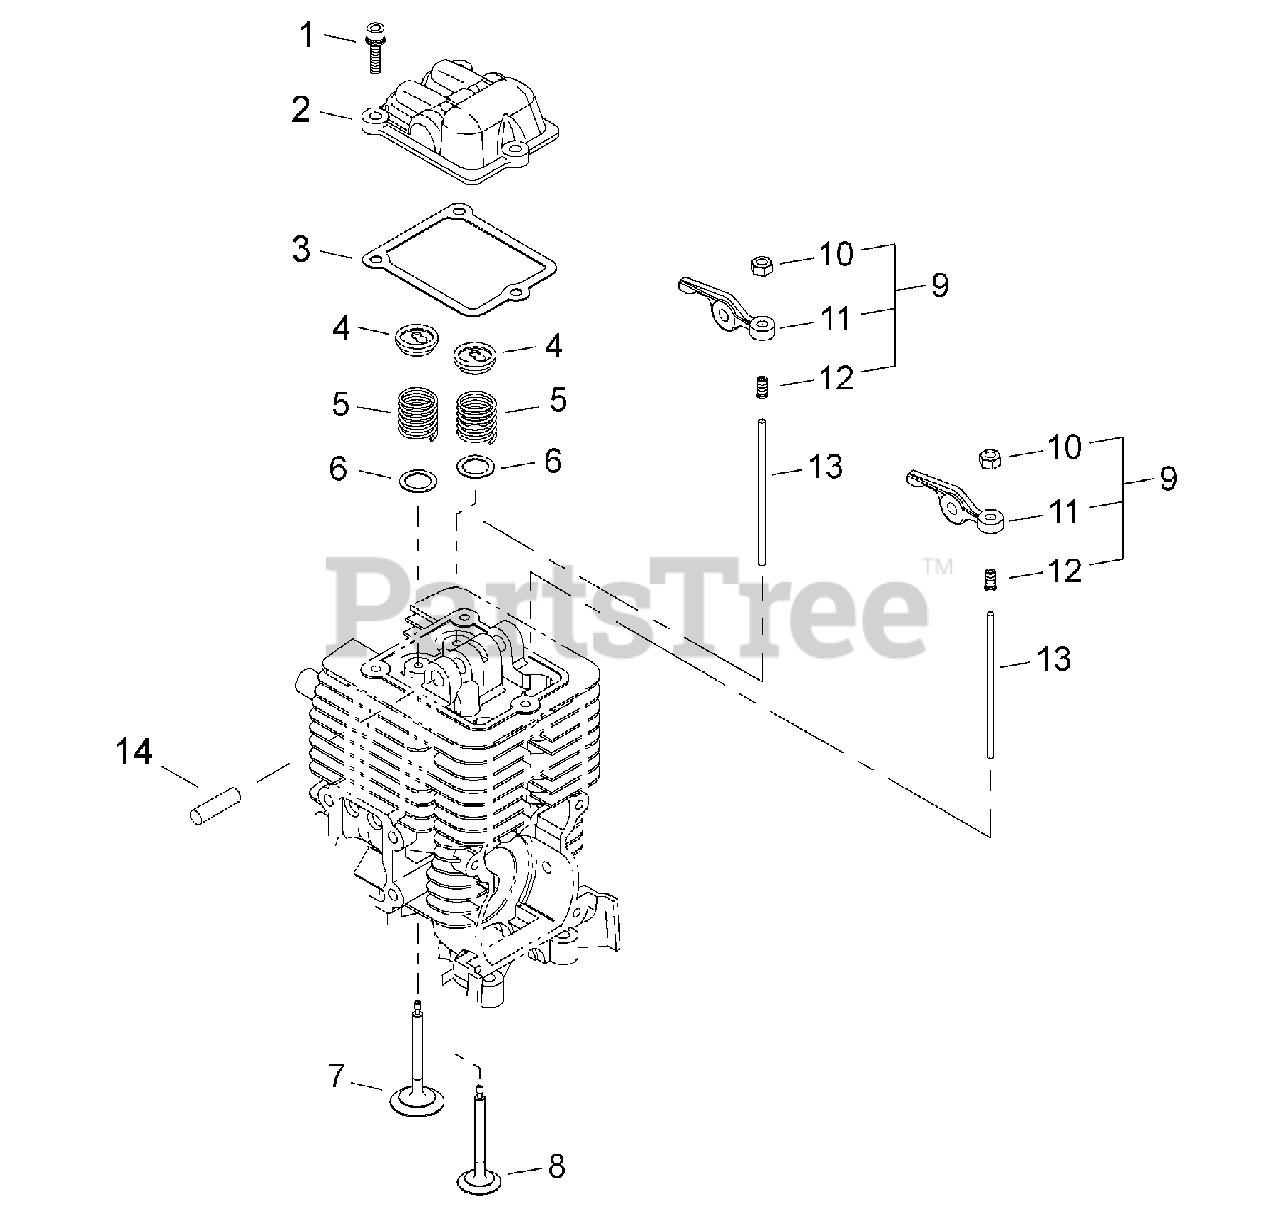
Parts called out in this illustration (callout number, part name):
1	SCREW - 4X14
2	COVER, ROCKER ARM
3	GASKET
4	RETAINER, VALVE
5	SPRING, VALVE
6	WASHER, VALVE - 9
7	VALVE, INTAKE
8	VALVE, EXHAUST
9	ROCKER ARM ASSY
10	LOCKNUT, ADJUSTER
11	ARM, ROCKER
12	SCREW, ADJUST
13	PUSHROD
14	SHAFT, ROCKER ARM - 5X37.8
